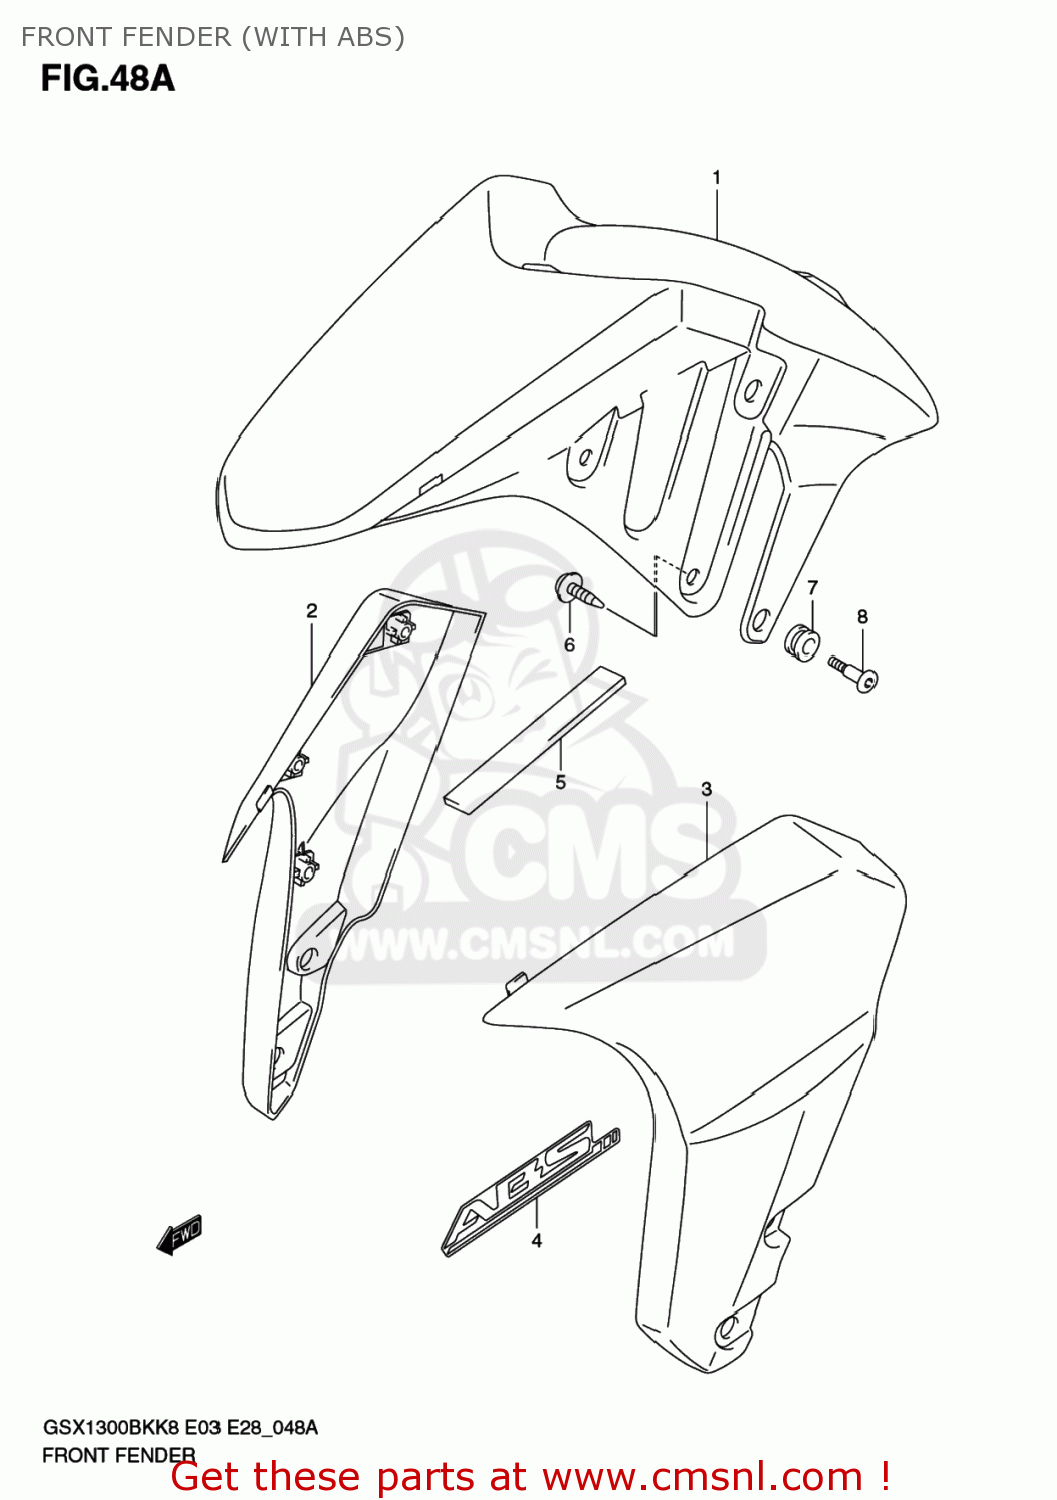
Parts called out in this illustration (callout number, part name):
1	FENDER,FR
2	COVER,FR FENDER SIDE,R(BLACK)
3	COVER,FR FENDER SIDE,L(BLACK)
4	EMBLEM,ABS
5	CUSHION,FR FENDER SIDE COVER
6	SCREW(5X15)
7	CUSHION
8	SCREW(6X16)
